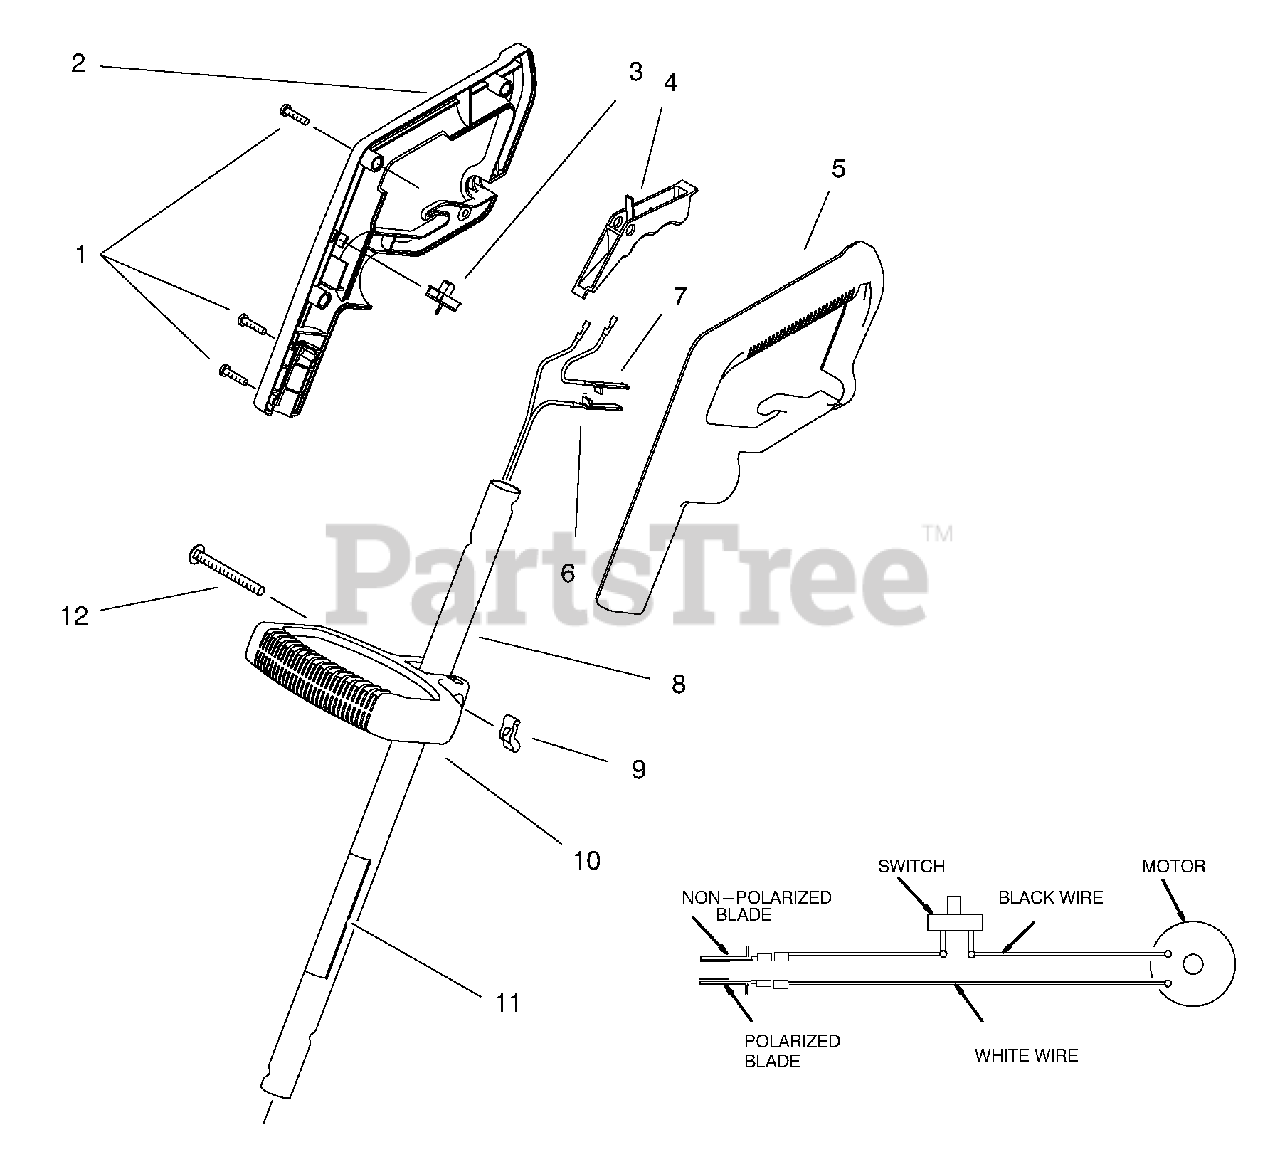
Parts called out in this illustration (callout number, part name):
1	Screw-Pan Hd Tapping
2	Grip-Hand R.H.
3	Switch-Single Speed
5	Grip-Hand L.H.
6	Harness-Wire
7	Jumper Wire Asm
8	Tube Assembly (Incl. Ref. #11)
10	Handle-Mid
11	Decal-Safety
12	Screw-Carriage
